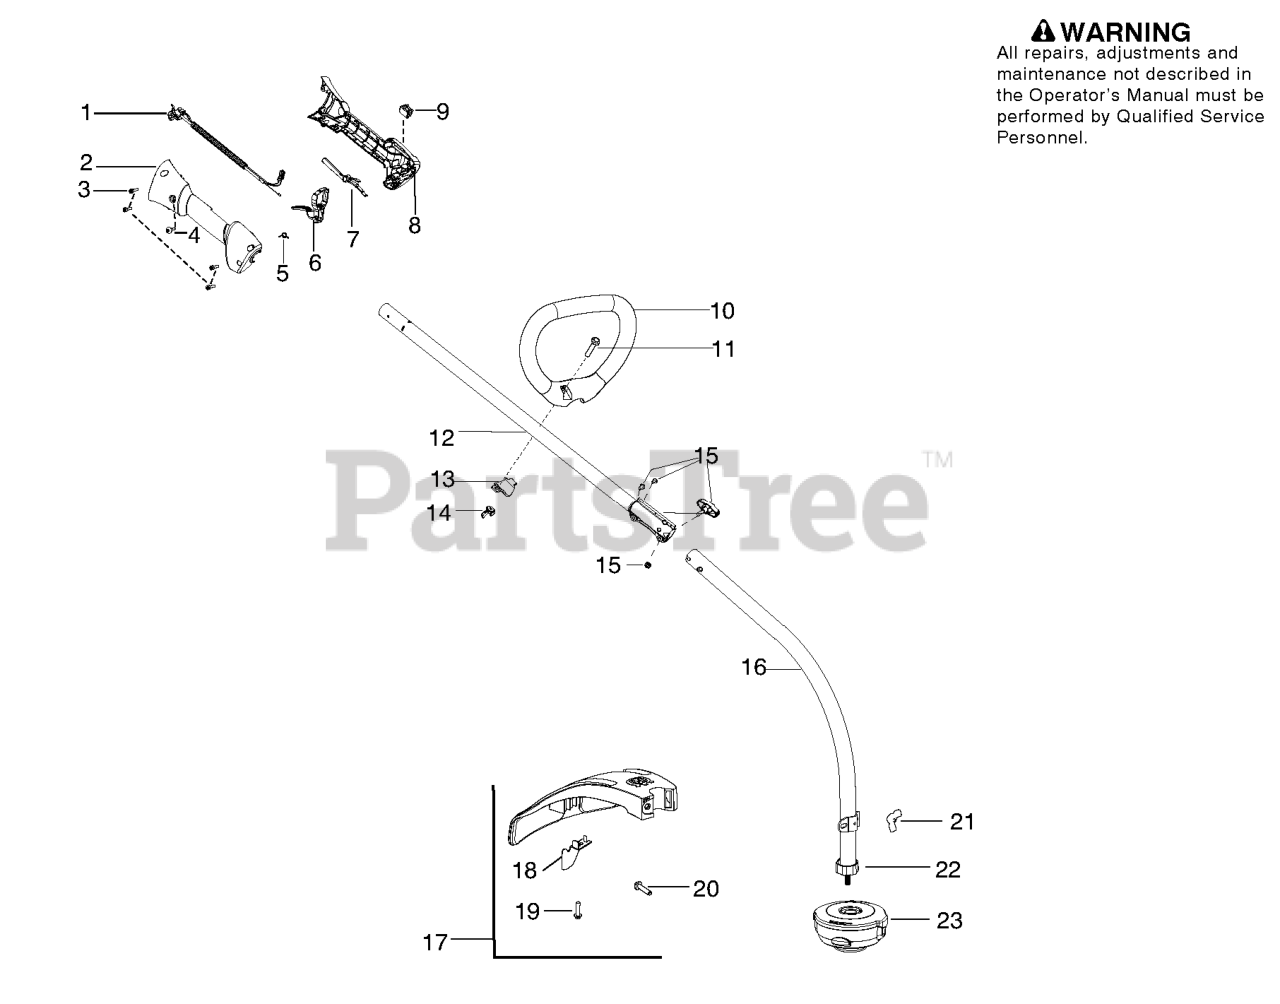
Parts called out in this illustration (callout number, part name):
1	Assy - Cable/Wire Harness
2	Housing - Throttle (RH)
3	Screw
4	Screw
5	SPRING TRIGGER
6	Trigger
7	Lockout - Throttle
8	Housing - Throttle (LH)
9	Kit - Switch
11	BOLT, TYPE 2
12	KIT UPPER SHAFT SILVER
13	CLAMP ASSIST HANDLE
14	WINGNUT, TYPE 2
15	ASSY COUPLER BLACK
16	KIT DRIVESHAFT
17	TRIMMER GUARD 128C
20	BOLT, TYPE 2
21	WINGNUT, TYPE 2
22	Dust Cup
23	Assy. - T25 Cutting Head
